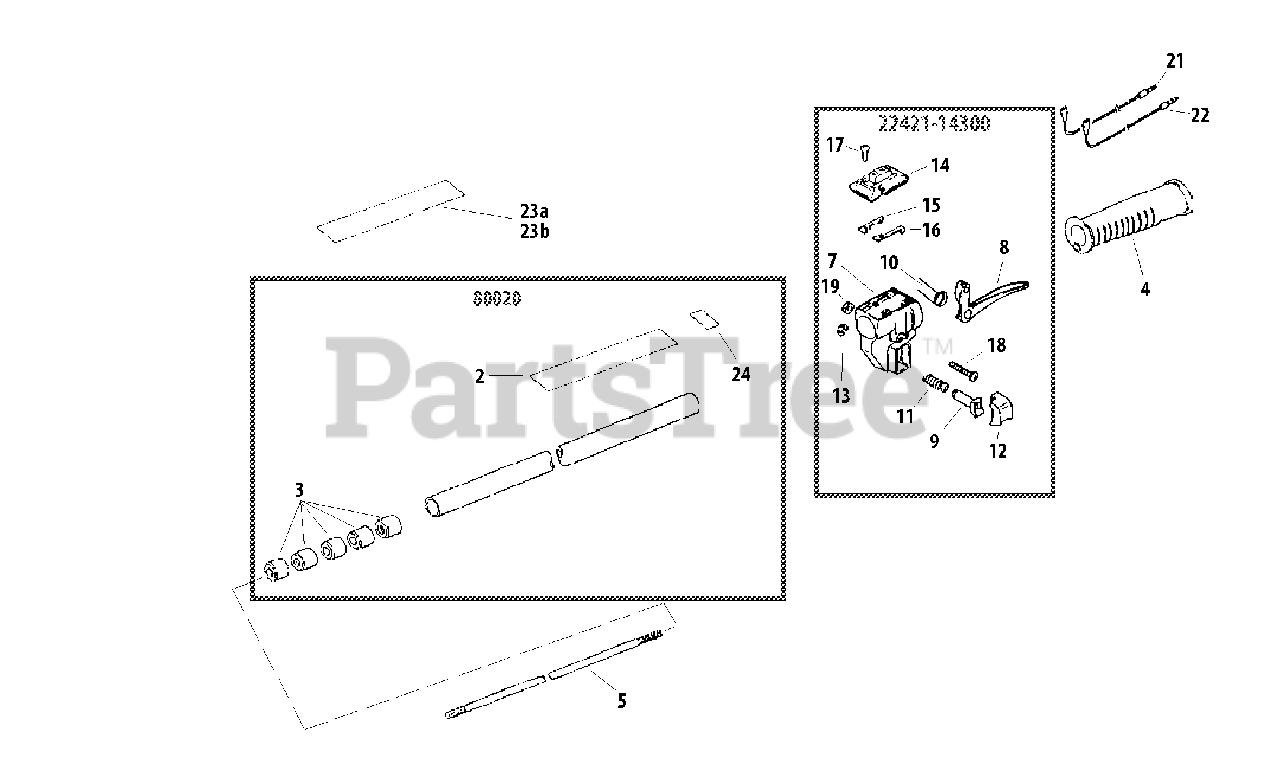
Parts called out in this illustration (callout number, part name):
2	LABEL, CAUTION (NON-BLADE CAPABLE)
3	BUSHING
4	GRIP, REAR
5	MAINSHAFT
7	BODY, THROTTLE
8	TRIGGER, THROTTLE
9	LOCKOUT, THROTTLE
10	SPRING, RETURN
11	SPRING
12	BUTTON, THROTTLE LOCK
13	RING, SNAP
14	SWITCH, ON-OFF
15	PLATE, RIGHT GROUND
16	PLATE, LEFT GROUND
17	SCREW, TAPPING
18	SCREW
19	NUT, NYLON
21	WIRE, RIGHT LEAD
22	WIRE, LEFT LEAD
23A	LABEL - MODEL
23B	LABEL
24	LABEL, HANDLE
22421-14300	THROTTLE CONTROL ASSY
80020	MAIN PIPE ASSY
